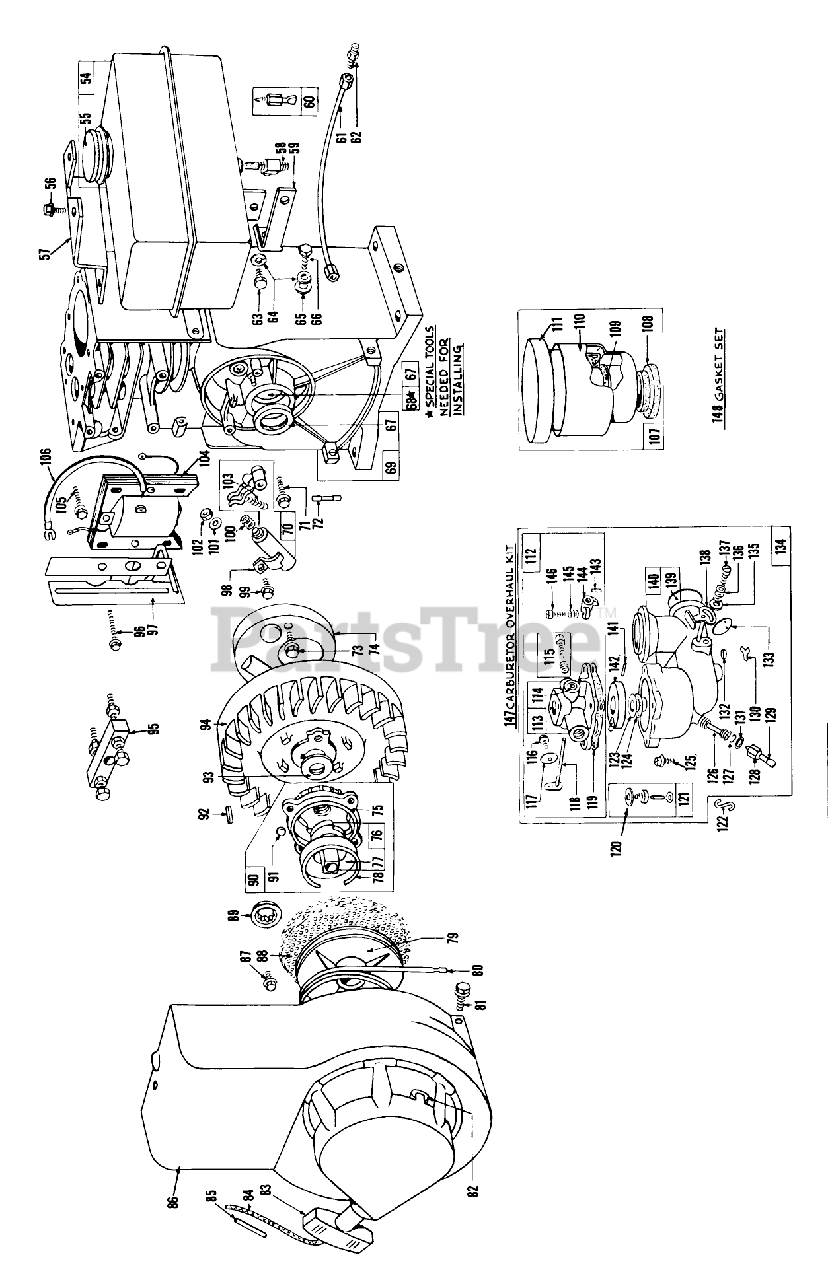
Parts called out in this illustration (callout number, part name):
54	Tank Assy., Fuel
55	Cap-Fuel Tank
56	Screw, Tank Mtg., Sem
57	Support-Fuel Tank
58	Outlet, Fuel Tank (includes strainer)
59	Bracket-Fuel Tank
60	Valve-Shut Off
61	Pipe, Fuel
62	Connector, Fuel Pipe
63	Screw, Cap, Hex. Hd.,
64	Washer-Lock
65	Washer-Plain
66	Screw, Cap, Hex. Hd.,
67	Seal-Oil
68	Bushing
69	Cylinder Assy.
71	Screw, Armature Mtg. Sem
72	Plunger
73	Screw
74	Cover Breaker Pt. Cond.
75	Housing, Starter Clutch
76	Ratchet, Rewind Starter
77	Washer, Clutch Retainer (used with sq. shank ratchet)
78	TUBE ASSY - BRAKE
79	Pulley, Rewind Starter
80	Spring-Rewind
81	Screw
82	Bumper, Starter Pulley
84	Rope, Starter,
85	Pin-Starter Grip
86	Housing, Blower
87	Screw
88	Screen, Starter Pulley
89	Washer, Ratchet Sealing
90	Clutch Assy., Rewind Starter
91	Ball
92	Key Flywheel
93	Washer, Sprg. (use to lock rewind starter clutch)
94	Flywheel Assy.
95	Puller-Flywheel
96	Screw, Armature Mtg. Sem
97	Blade, Governor
98	Camp-Condenser
99	Screw
100	Spring Connector
101	Washer-Lock
103	Spring Breaker Arm
104	Armature, Magneto
105	Screw, Armature Mtg. Sem
106	Cable, Ignition
107	Cleaner Assy., Air (with mtg. stud)
108	Body-Breather
109	Gasket, Air Cleaner
110	Bowl, Air Cleaner
111	Cover and Filter, Air Cleaner (with Mtg. stud)
112	Housing Assy., Throttle
113	Body, Upper Carburetor
114	Bushing-Throttle Shaft
115	Valve Assembly
116	Screw, Throttle Valve Mtg. Sem
117	Valve, Throttle
118	Shaft/Lever-Throttle
119	Gasket-Carburetor Body
120	Gasket, Fuel Inlet Valve Seat
121	Valve Seat-Fuel Inlet
122	Link-Governor
123	Venturi-Carburetor
124	Gasket-Venturi
125	Screw, Throttle Housing
126	Nozzle, Carburetor
127	Packing, Needle Valve
128	Nut, Needle Valve Packing
129	Valve, Needle
130	Retainer, Carb. Drain Filter
131	Washer, Needle Valve Pkg.
132	Filter-Carburetor Drain
133	Valve-Choke
134	Carburetor Assy.
135	Washer-Choke Lever
136	Spring-Choke Lever
137	432/434/13933A GILS
138	Shaft and Lever Assy.
139	Plug-Welch
140	Body Assy., Carburetor
141	Pin-Float Hinge
142	Float-Carburetor
144	Stop-Throttle
145	Spring
146	Screw
147	Carburetor Overhaul Kit
